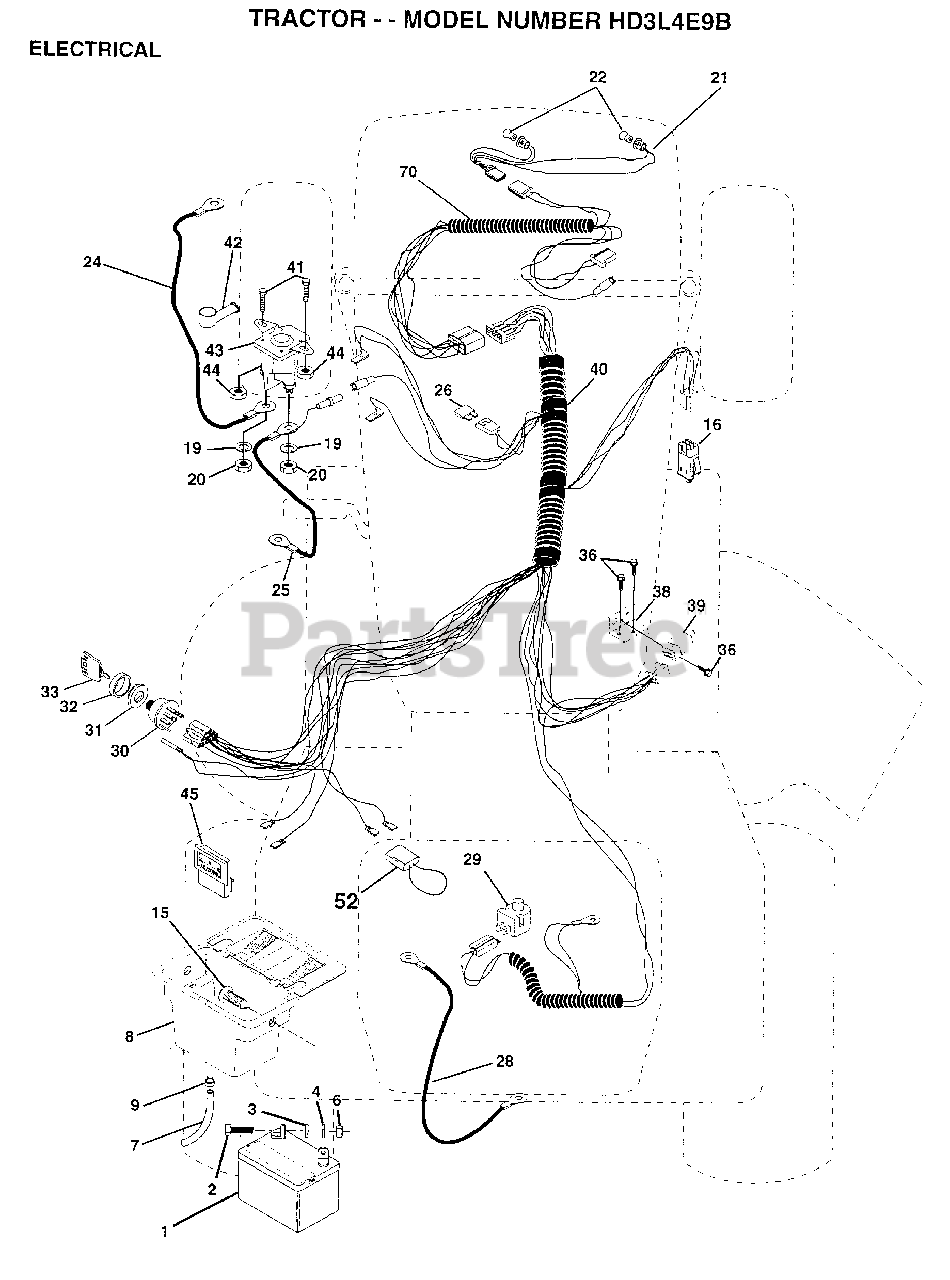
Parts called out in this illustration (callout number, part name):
2	BOLT LT
3	WASHER
4	LOCKWASHER
7	TUBE T
9	HOSE CLAMP T
15	FASTNER.SNAP-IN
16	SWITCH INTERLOCK
20	NUT
21	"HARNESS,LIGHT SOC"
22	HEADLAMP BULB
24	CABLE-BATTERY T
25	CABLE.BTRY.6GA.RD
26	FUSE HYT
28	CABLE T
29	SWITCH SEAT
30	SWITCH IGN 4POS
31	NUT IGNITION
32	COVER KEY SWITCH
33	KEY
36	SCREW
38	BRACKET SWITCH IN
39	SWITCH INTERLOCKT
40	HARNESS.IGNITION
41	BOLT HXHD FIN
44	NUT HXKEP 1/4X20
52	PROTECTION LOOP
70	HARNESS.ENG.LT.
